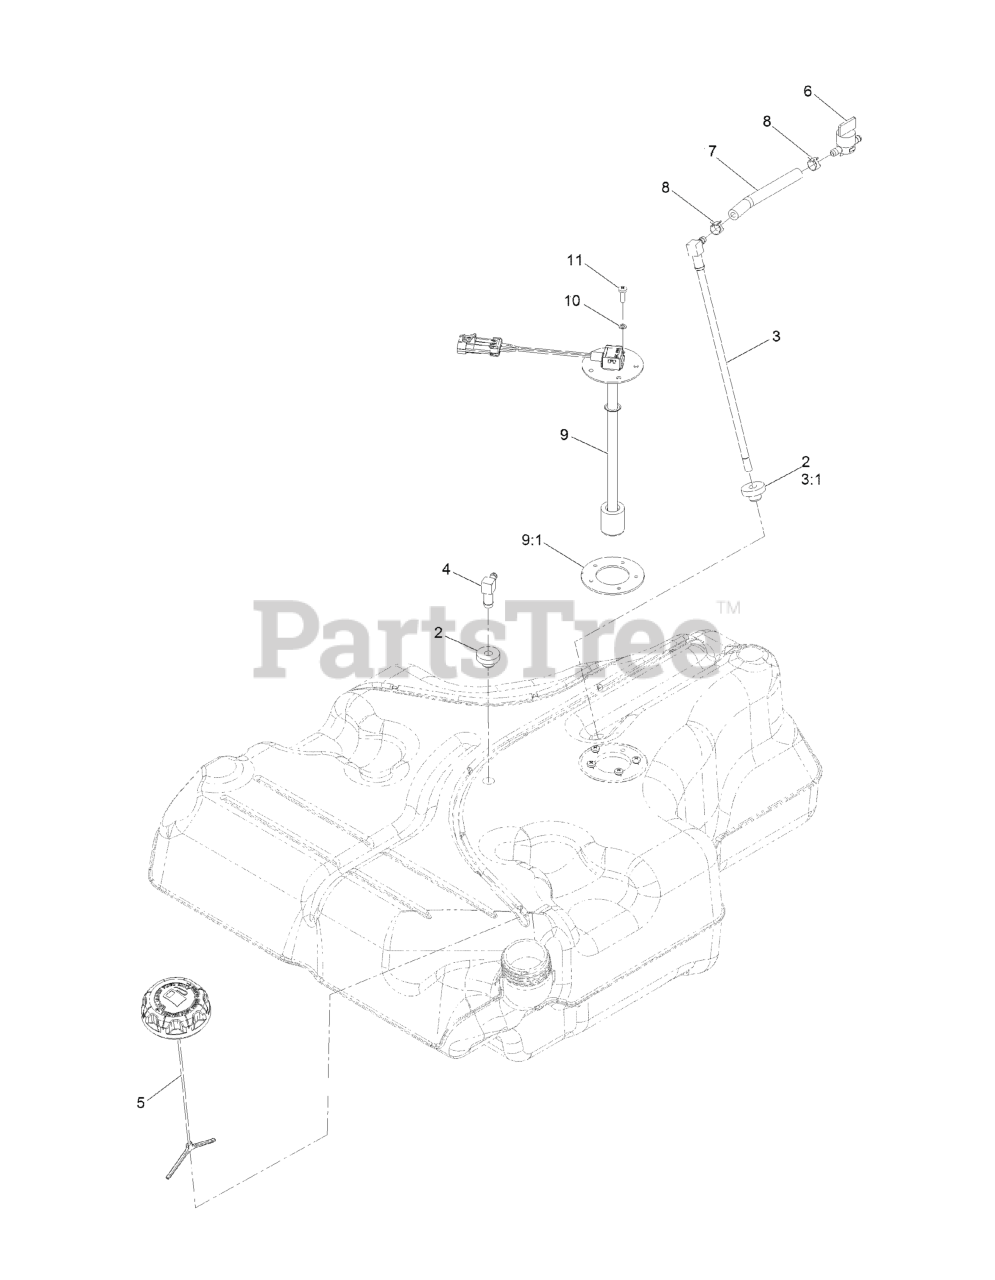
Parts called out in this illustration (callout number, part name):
2	BUSHING
3	FUEL LINE KIT (WITH GROMMET)
3:1	BUSHING
4	FITTING-90 ELBOW
5	CAP-FUEL, RATCHETING
6	VALVE-FUEL
7	HOSE-FUEL
8	CLAMP-HOSE
9	SENDER-LEVEL, FUEL (W/GAS
9:1	Gasket-Sender
10	WASHER-LOCK
11	SCREW-PPH
